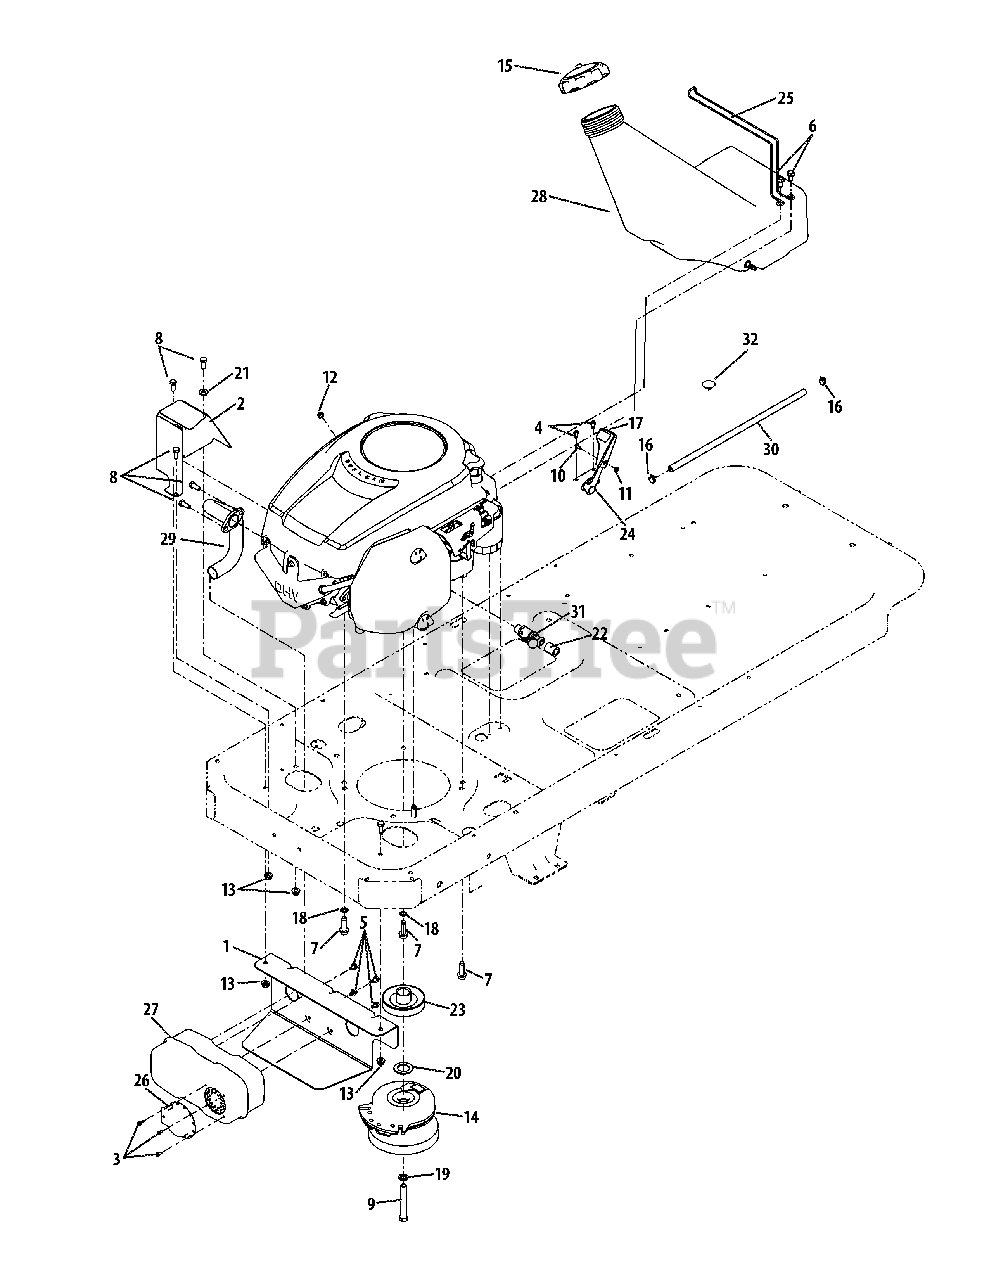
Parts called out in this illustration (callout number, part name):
1	Muffler Mounting Bracket
2	Muffler Tube Heat Shield
3	Hex Screw, #8-18 x .5
4	AB Screw, 1/4-14 x .625
5	Hex Screw, 1/4-20 x .5
6	Hex Screw, 5/16-18 x .750
7	Hex Screw, 3/8-16 x 1.250
8	Hex Screw, 5/16-18 x .75
9	Hex Screw, 7/16-20 x 3.25
10	Machine Screw, #8-32 x .375
11	Hex Nut, #8-32
12	Sems Nut, 1/4-20
13	Flange Lock Nut, 5/16-18
14	Electric PTO Clutch
15	Fuel Cap
16	Hose Clamp, .490
17	Throttle/Choke Control Knob
18	External Tooth Lock , 3/8
19	Lock , 7/16
20	Flat Washer, 1.031 x 1.620 x .095
21	Flat Washer, .344 x .750 x .120
22	Oil Drain Hose
23	PTO Pulley
24	Throttle Cable, 39.0 x .62
25	Tank Mounting Wire
26	Muffler Deflector
27	Single Inlet Muffler
28	Fuel Tank
29	Exhaust Pipe
30	Fuel Hose
31	Oil Drain
32	Choke Plug
